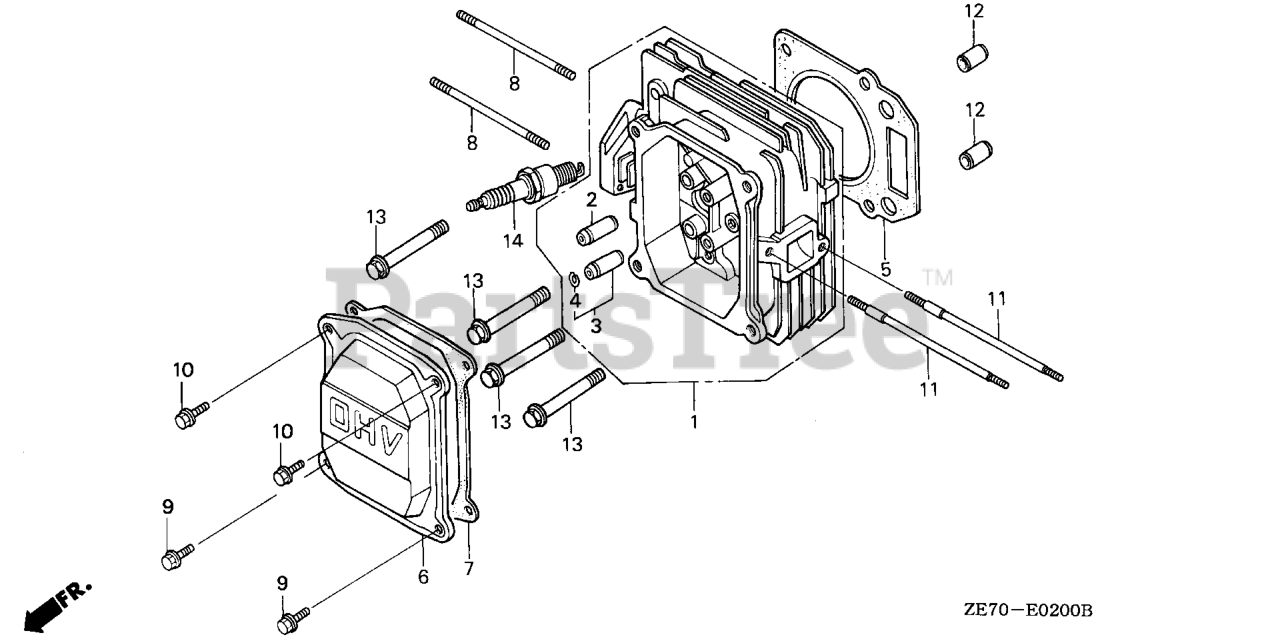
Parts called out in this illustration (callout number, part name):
1	CYLINDER HEAD
2	GUIDE, VALVE (OVER SIZE) Use from Engine SN 6324986.
4	CLIP, VALVE GUIDE Use from Engine SN 1231803.
5	GASKET, CYLINDER HEAD
6	COVER, HEAD
7	GASKET, CYLINDER HEAD COVER
8	BOLT, STUD (6X85)
9	BOLT, FLANGE (6X12) (CT200)
10	BOLT, FLANGE (6X12) (CT200)
11	BOLT, STUD (6X109)
12	PIN A, DOWEL (10X16)
13	BOLT, FLANGE (8X50)
14	SPARK PLUG (BPR4ES) (NGK)
14	SPARK PLUG (W14EPR-U) (DENSO)
14	SPARK PLUG (BPR5ES) (NGK)
14	SPARK PLUG (W16EPR-U) (DENSO)
14	SPARK PLUG (BPR6ES) (NGK)
14	SPARK PLUG (W20EPR-U) (DENSO)
